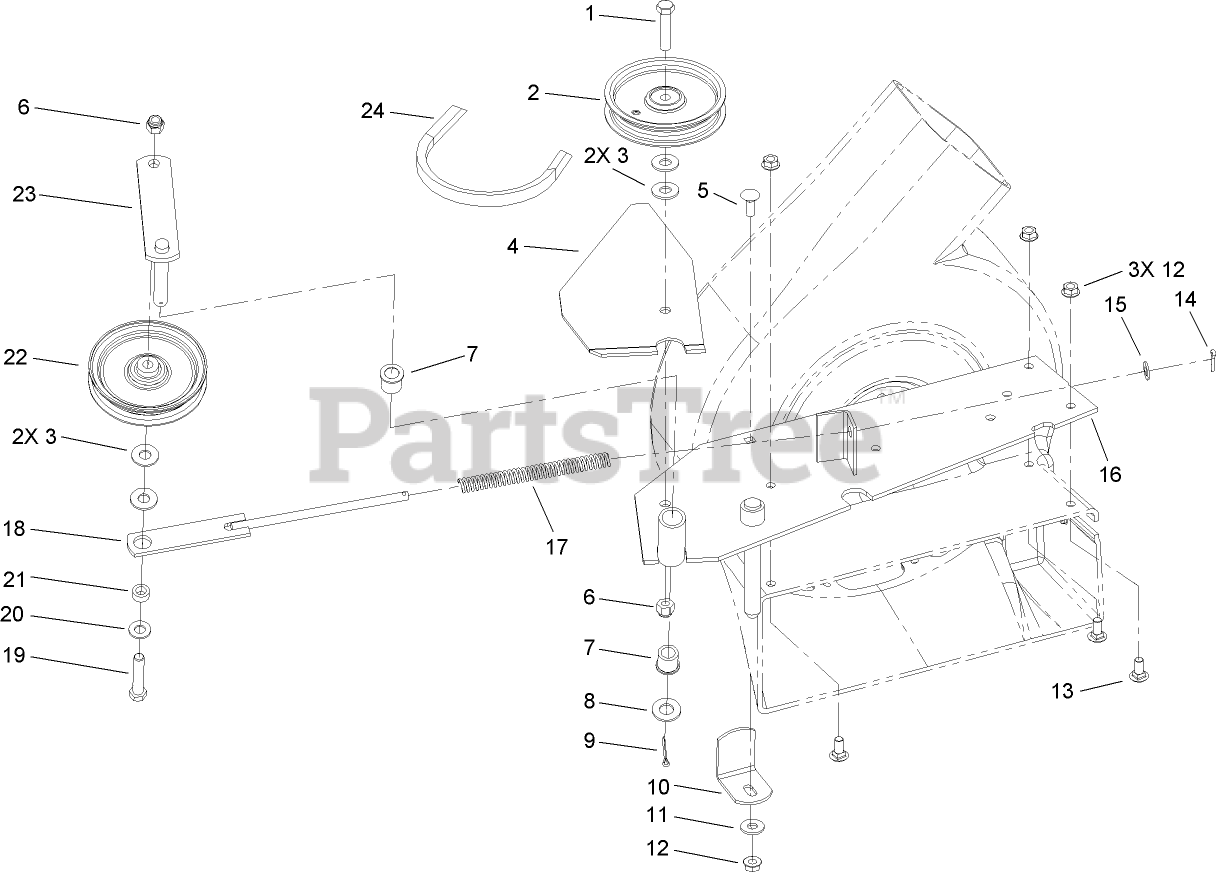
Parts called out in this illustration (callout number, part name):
1	SCREW-HH
2	PULLEY-IDLER
3	WASHER-FLAT
4	SUPPORT-SHIELD, BELT
5	SCREW-CARR
6	NUT-LOCK, NI
7	BUSHING
8	WASHER-FLAT
9	PIN-COTTER
10	BRACKET-SUPPORT, HOUSING
11	WASHER-FLAT
12	NUT-HF
13	BOLT-CARR
14	PIN-COTTER
15	WASHER-PLAIN
16	BLOWER MOUNTING ASM
17	SPRING-COMPRESSION
18	SPRING-ROD
19	SCREW-HH
20	WASHER-FLAT
21	SPACER
22	PULLEY-IDLER
23	IDLER ARM ASM
24	V-BELT
